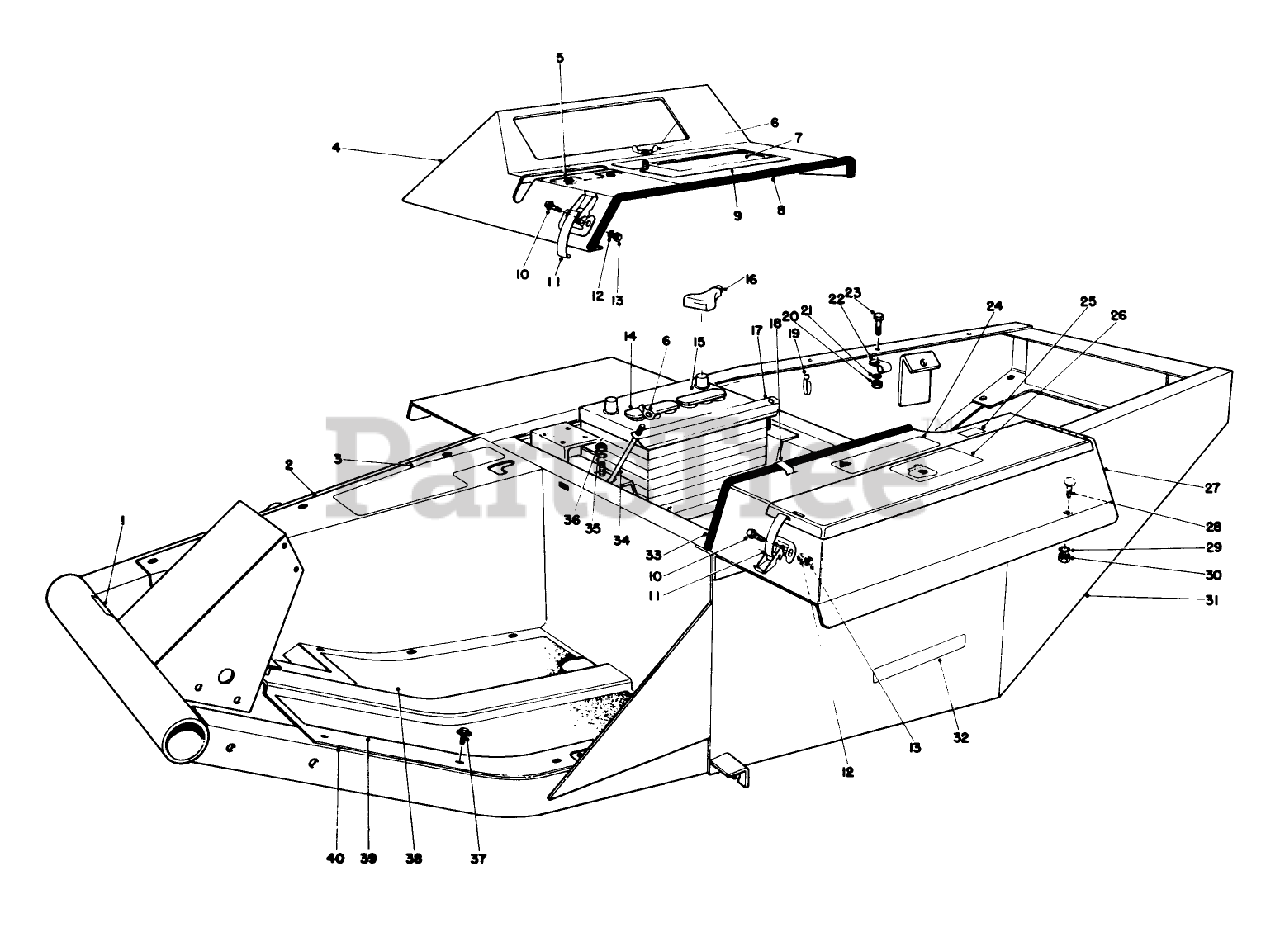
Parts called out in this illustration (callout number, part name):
1	DECAL-PEDAL, TRACTION
2	Footrest
3	Decal Caution
4	Cover-Instrument
5	DECAL-PTO
6	NUT-WING
7	Decal Starting Instructions
8	TRIM-COVER, INSTRUMENT
9	Cover Battery Access
10	SCREW-SHWH
11	CLAMP-SLOTTED
12	WASHER-LOCK
13	NUT-HEX
14	PUSH-ON BATTERY CAP
15	Battery (Incl. Ref. #14)
16	BOOT-CABLE, BATTERY
17	Battery Hold Down
18	TINNERMAN CLIP
19	TIE-CABLE
20	NUT-HEX
21	WASHER-LOCK
22	CLAMP-R
23	SCREW-HH
24	Decal Caution
25	DECAL GAS
26	DECAL-REFUELING
27	Box-Tool
28	SCREW-CARR
29	WASHER-LOCK
30	NUT-HEX
31	Frame
32	Decal Torque
33	TRIM-BOX, TOOL
34	STUD-HOLDDOWN, BATTERY
35	WASHER-LOCK
36	NUT-HEX
37	SCREW-HWH
38	PAD-FLOOR PLATE, RH
39	PAD-PLATE FLOOR, LH
40	Floor Plate
